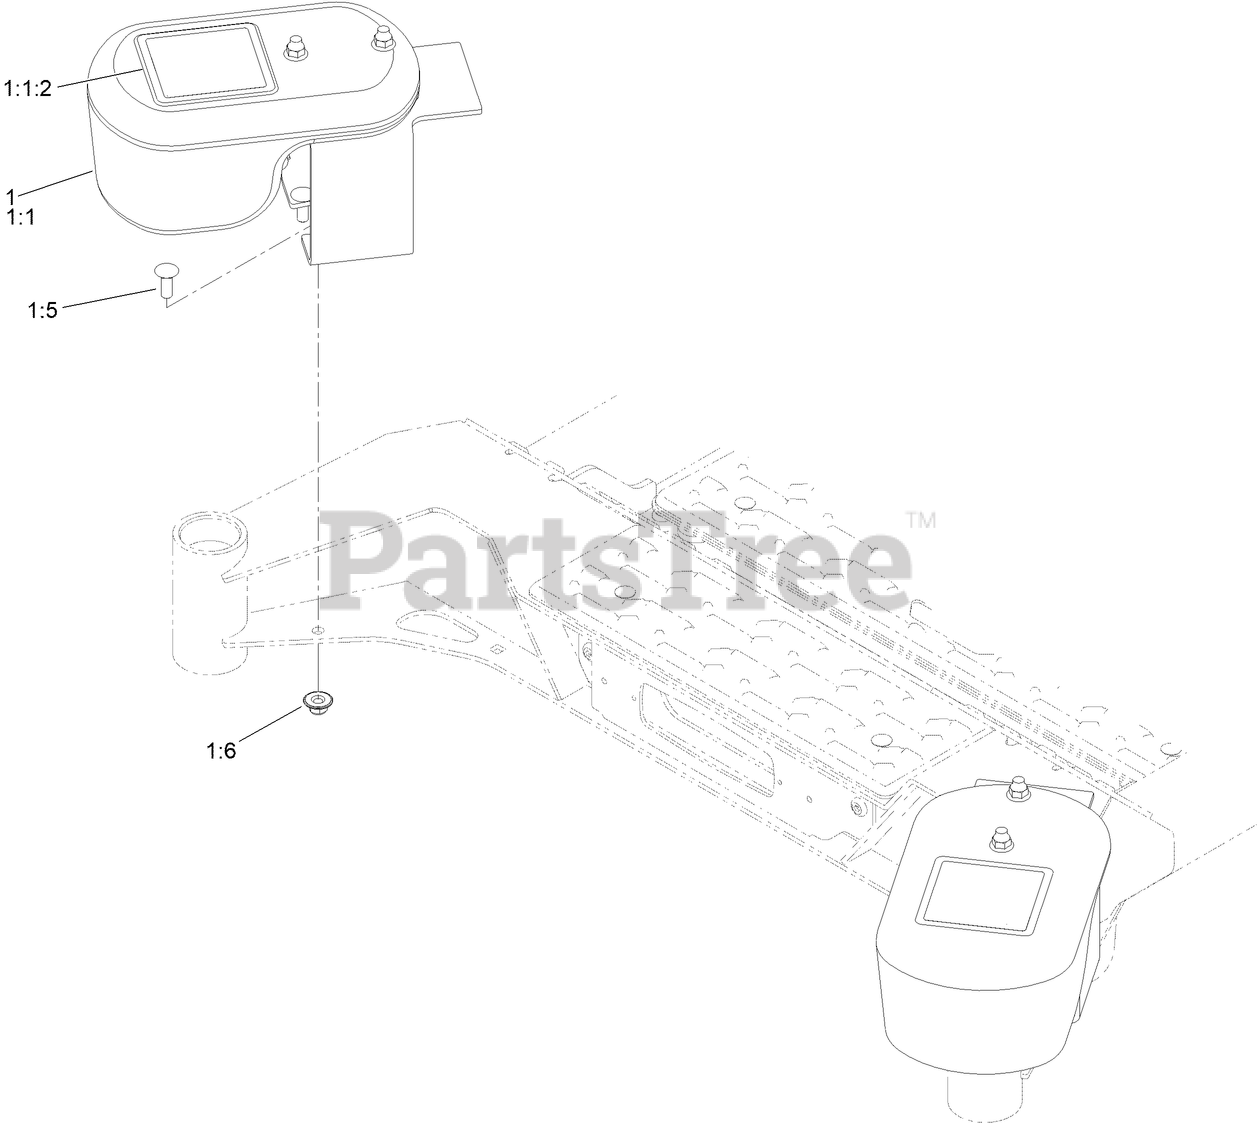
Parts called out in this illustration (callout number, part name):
1	ASM-CASTER WEIGHT
1:1	WEIGHT WITH DECAL ASM
1:1:2	DECAL-WARNING, TRACTION
1:5	SCREW-CARR
1:6	NUT-FLANGE, NI
